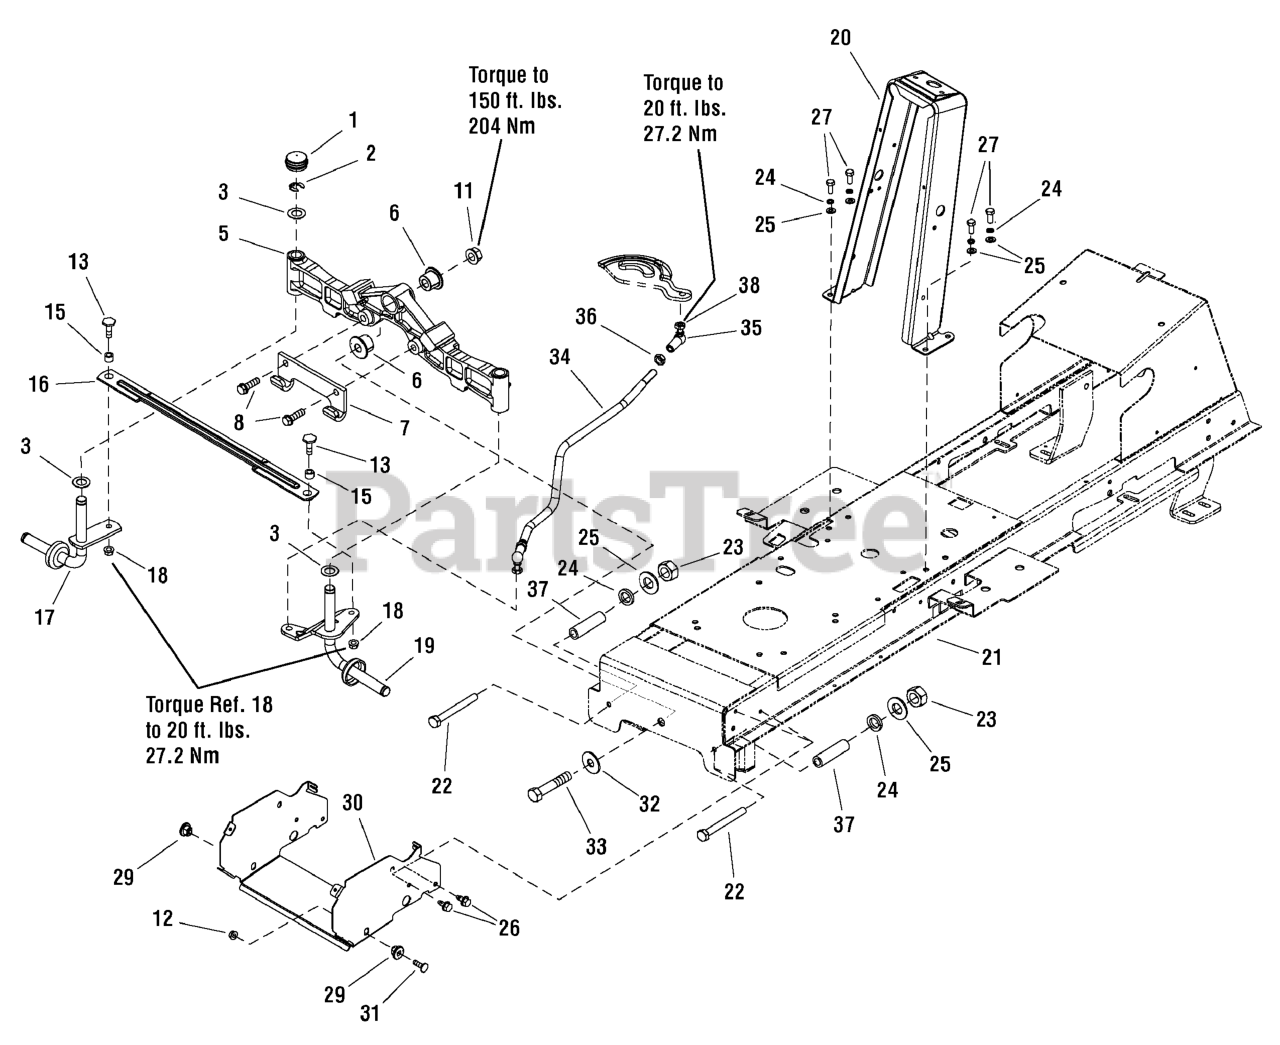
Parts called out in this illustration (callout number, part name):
1	CAP, Hub 1.51D
2	RING, Klipring
3	WASHER, 828 x 1.62 x .0583
5	AXLE, Front
6	BUSHING, Axle Pivot
7	HOOK, Hitch, 5/16
8	CAPSCREW, 7/16-14 x 1-1/2
11	NUT, Hex Flange, 5/8-11
12	NUT, Hex Flange, 5/16-18
13	SCREW, Hex Head, 3/8-16 x 1 1/4
17	SPINDLE AND CUP ASSEMBLY, Right
18	NUT, Hex Flange, 3/8-16
19	SPINDLE AND CUP ASSEMBLY, Left
20	TOWER
22	BOLT, M8 x 75
24	WASHER, 8.4
25	WASHER, 8
26	SCREW, Tap 5/16-18 x 5/8
27	BOLT, M8 x 20
29	PIVOT, Hood
30	SUPPORT, Muffler
31	BOLT, Carriage, Short Neck, 5/16-18 x 1
32	WASHER, 5/8
33	CAPSCREW, Hex Head, 5/8-11 x 3 1/4
34	DRAG LINK
35	BALL JOINT, CS16 M10-M12
36	NUT, M12
37	DISTANCE, Front Axle 0-9521-291
38	NUT, M10
